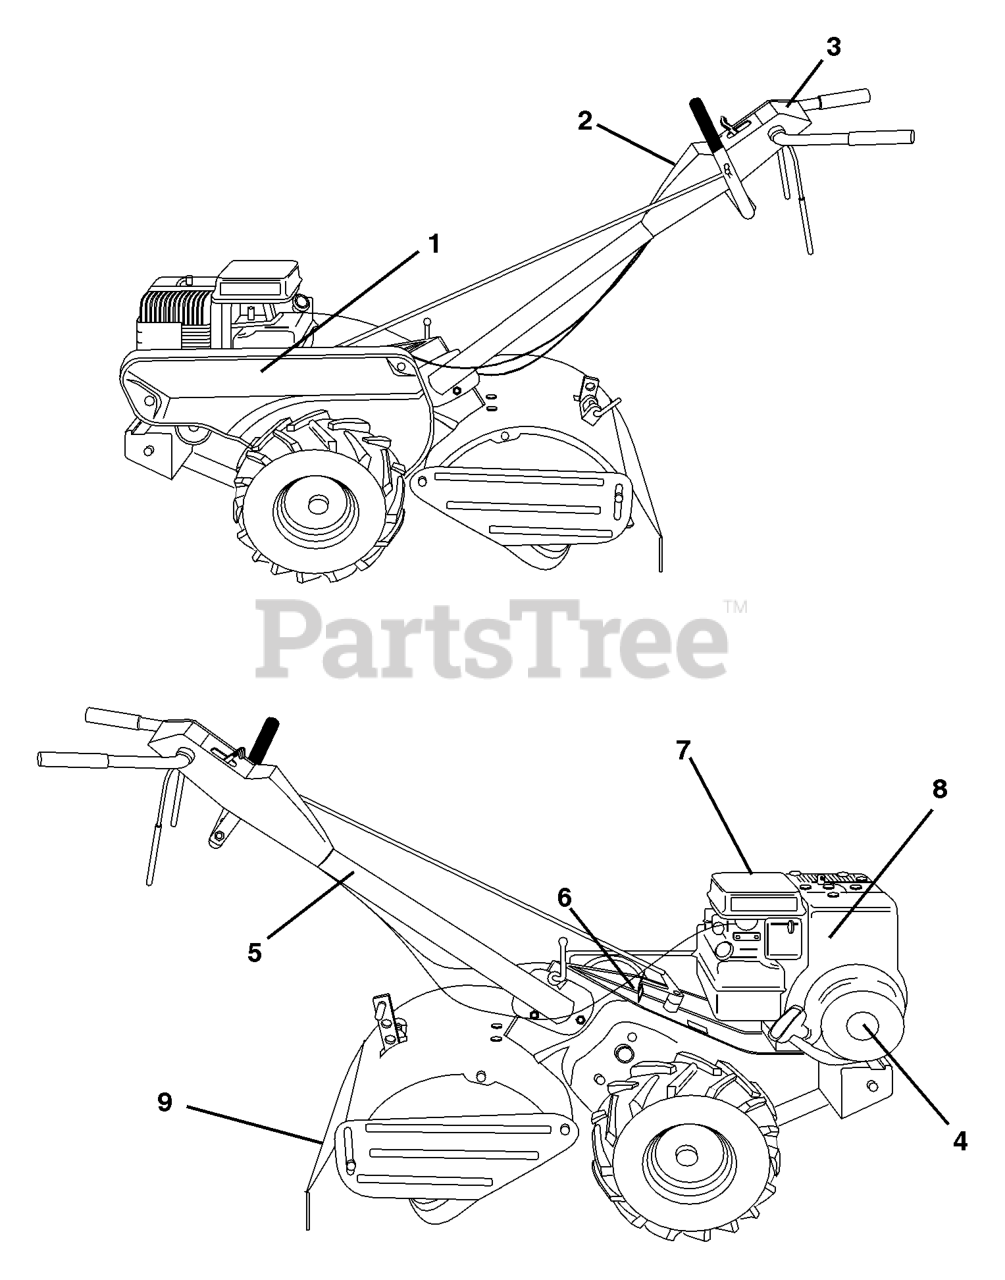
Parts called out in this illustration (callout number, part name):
1	Decal, Logo
2	DECAL, LOGO
3	DECAL, LOGO
5	DECAL TI (2 2)
6	Decal, Shift Indicator
7	DECAL -CAUTION
8	DECAL, B & S ENGINE
9	DECAL TI
